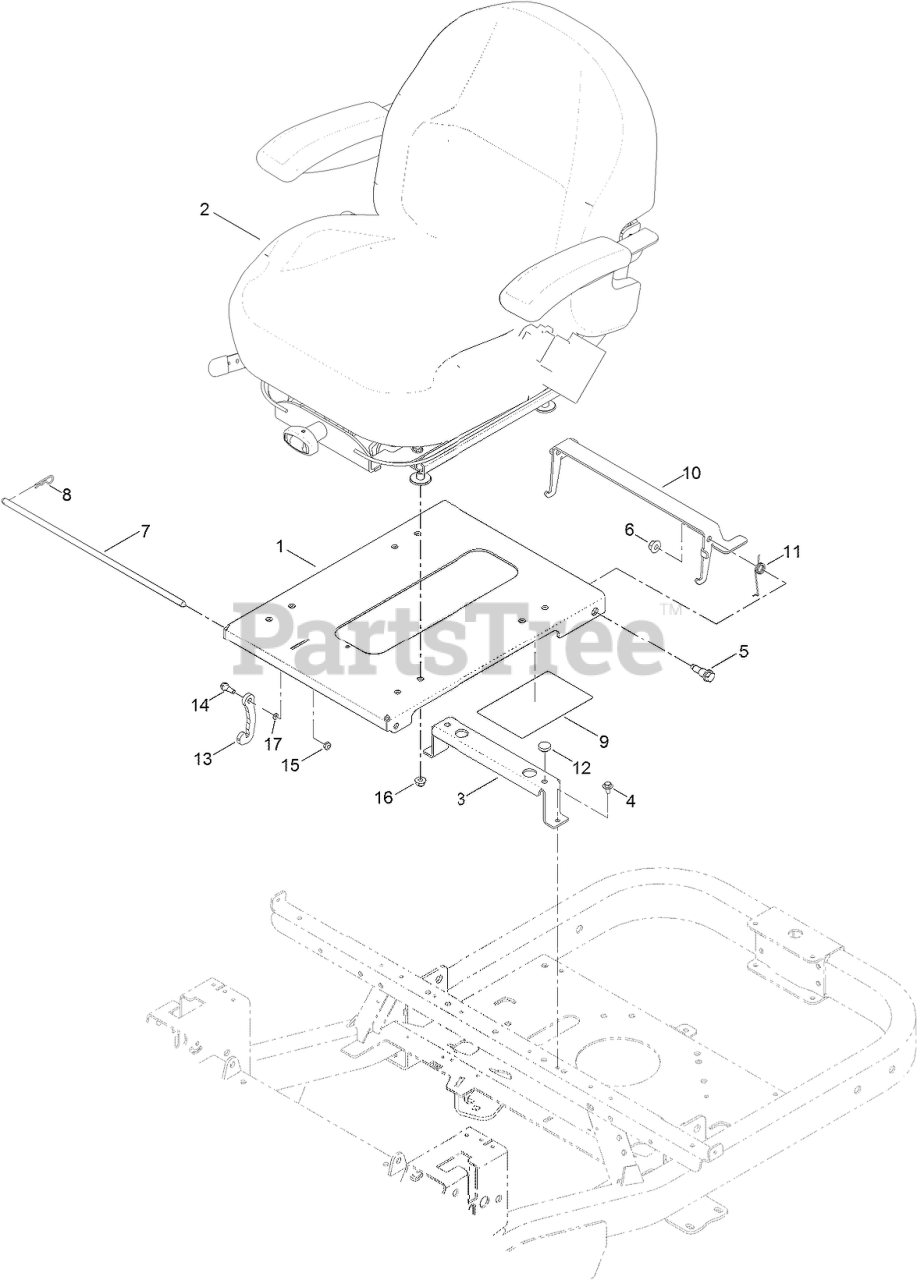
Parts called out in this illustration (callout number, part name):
1	SEAT PAN ASM
2	SEAT ASM
3	SEAT-SUPPORT, REAR
4	SCREW-HHFTF
5	BOLT-SHOULDER
6	NUT-HF, NI
7	ROD-STOP
8	PIN-COTTER
9	DECAL-MAINTENANCE
10	LATCH-SEAT
11	TORSION-SPRING
12	BUMPER
13	STOP-SEAT
14	BOLT-SHOULDER
15	NUT-LOCK, NI
16	NUT-HF, NI
17	WASHER
